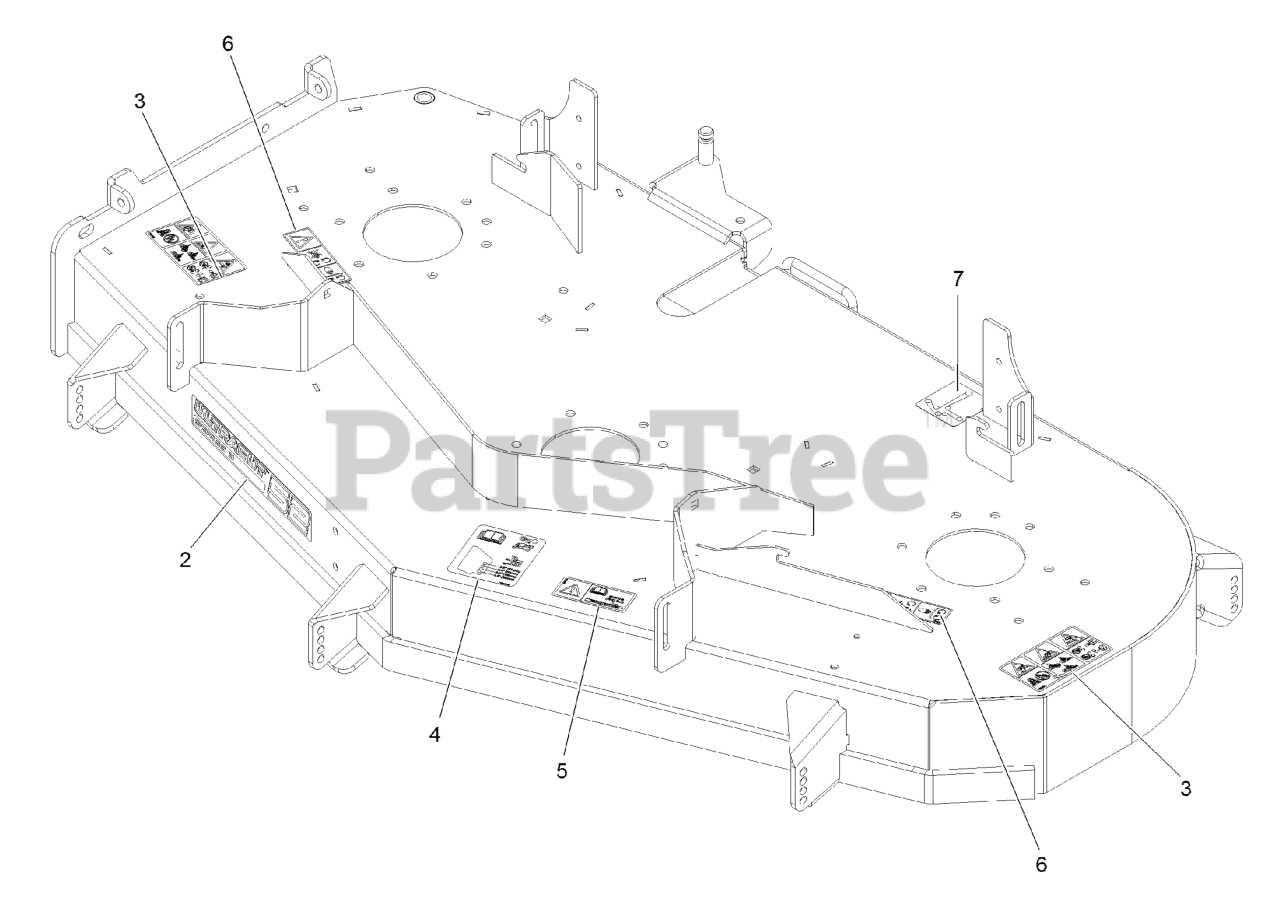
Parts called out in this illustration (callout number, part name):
2	DECAL-ULTRACUT 52 SERIES 3
3	DECAL-DANGER THROWN OBJECTS
4	DECAL-ROLLER, ANTI-SCALP
5	DECAL-TORQUE, BOLT
6	DECAL-COVER, MISSING
7	DECAL-ROUTING, BELT
